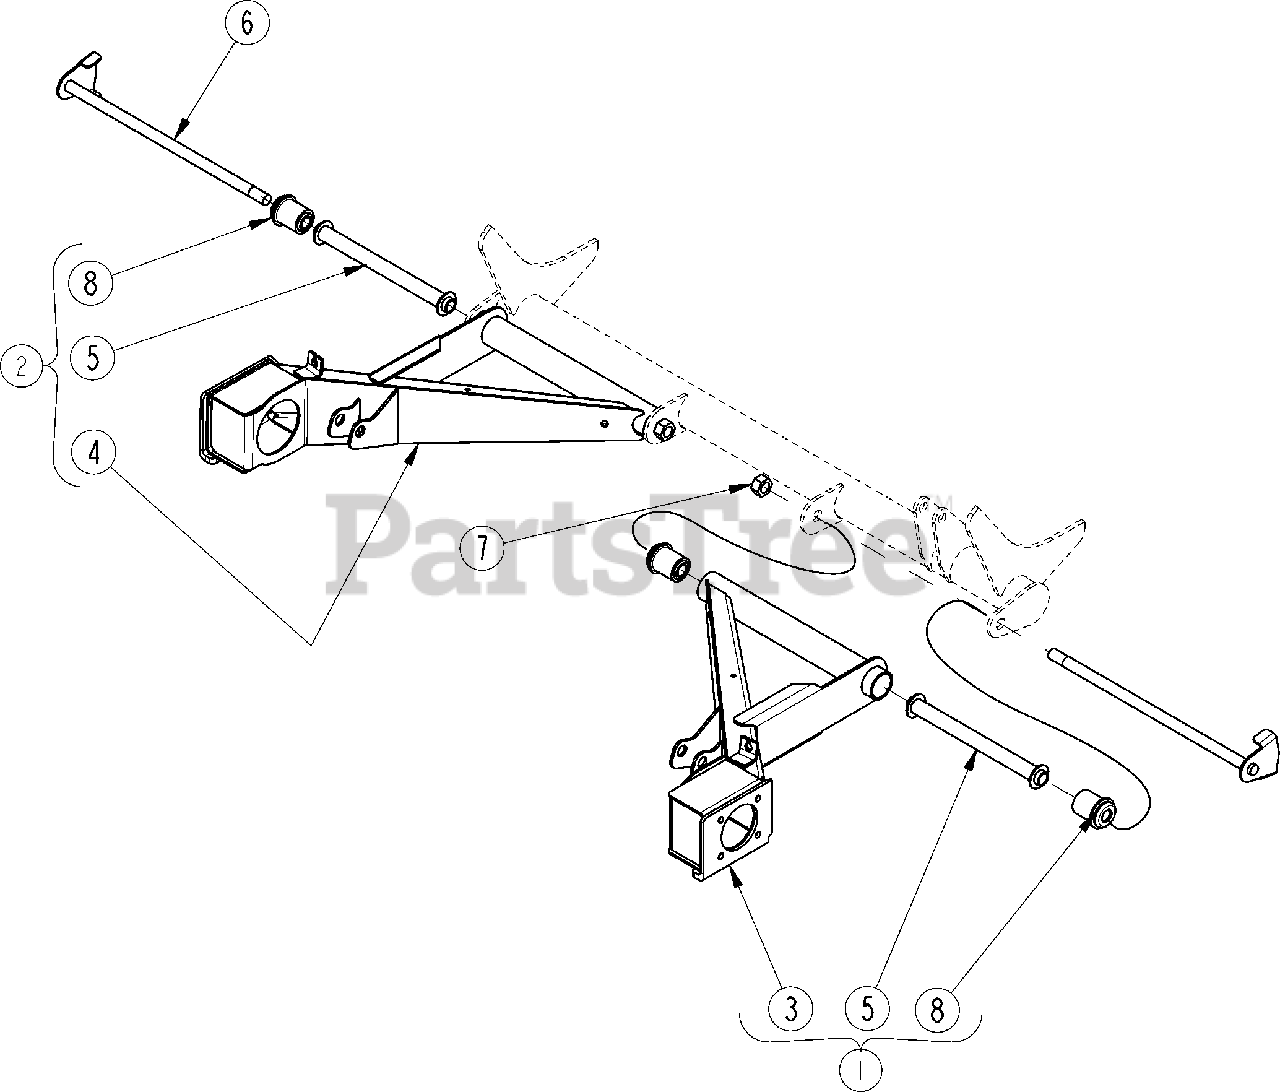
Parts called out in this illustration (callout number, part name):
1	TRAILING ARM RH ASSY
2	TRAILING ARM LH ASSY
3	TRAILING ARM RH WELDMENT
4	TRAILING ARM LH WELDMENT
5	CENTER PIVOT TUBE WELDMENT
6	TRAILING ARM PIVOT BOLT WLDMNT
7	NUT HEX TOP LOCK 9/16-12 YLW
8	BUSHING IDLER ARM RUBBER
